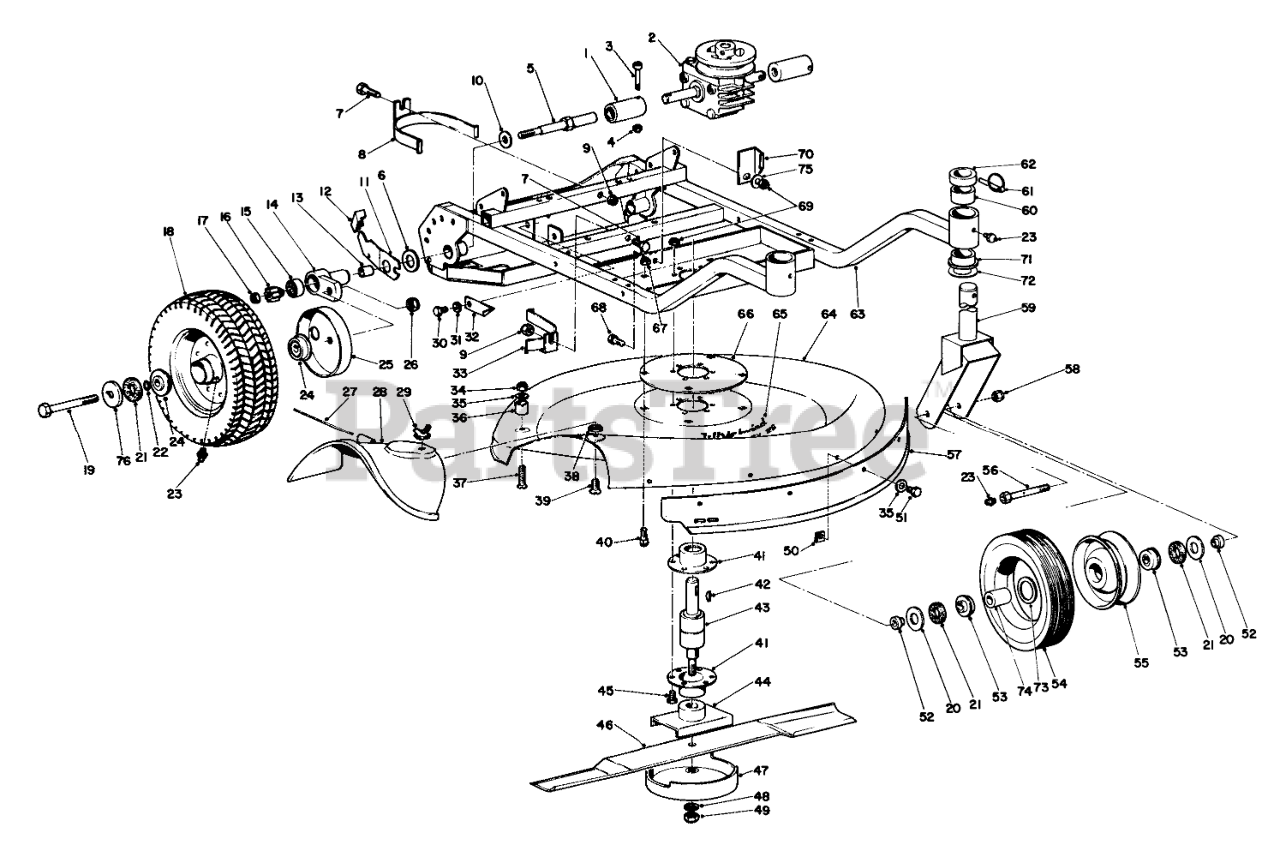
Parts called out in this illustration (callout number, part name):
1	Clutch Assembly R.H.
2	Transmission Assembly
3	DRIVE SCREW
4	NUT-LOCK, NI
5	DRIVE SPINDLE
6	Washer
7	SCREW-HH
8	Belt Retainer W.A.
9	NUT-LOCK, NI
10	Washer
11	RH SPRING ARM ASM
12	ARM KNOB
13	BUSHING
14	Pivot Arm Assy., Right
15	.375 RPP BALL BEARING
16	Pinion Kit
17	NUT-HJ
18	Rear Wheel Assy., (Incl. Ref. 24)
19	SCREW-HH
20	WASHER-FLAT
21	Washer
22	O-RING
23	FITTING-GREASE
24	BEARING
25	Wheel Cover
26	NUT-LOCK, NI
27	Hinge Pin
28	DEFLECTOR
29	Nut Wing
30	SCREW-HH
31	WASHER-LOCK
32	Retainer
33	Belt Retainer W.A.
34	NUT-KEPS
35	WASHER-FLAT
36	Spacer
37	Screw
38	PAL NUT
39	5/16-18X7/8 FLT HD MS
40	BOLT-CARR
41	BEARING HOUSING
42	KEY-WOODRUFF
43	Bearing Spindle
44	Retainer
45	SCREW-HH
46	Blade
48	WASHER-LOCK
49	NUT-HEX
50	SPEED NUT
51	SCREW-HH
52	CASTOR SPACER
53	BEARING-BALL
54	1.75-8 SEMIPNEU TIRE
55	Wheel (Incl. Ref. # 53)
56	AXLE BOLT
57	Cover
58	NUT-HEX
59	Caster Fork
60	7/8 ID X 1.128 X 7/8 LG BSHG
61	PIN-LYNCH
62	HT OF CUT SPACER
63	Frame W.A.
64	Housing
65	Decal
66	Plate
67	NUT-HEX
68	SCREW-HH
69	Nut
70	Belt Retainer
71	FLANGE BUSHING
72	WASHER
73	WASHER-SPECIAL
74	BRG SPACER
75	WASHER-PLAIN
76	SLINGER
